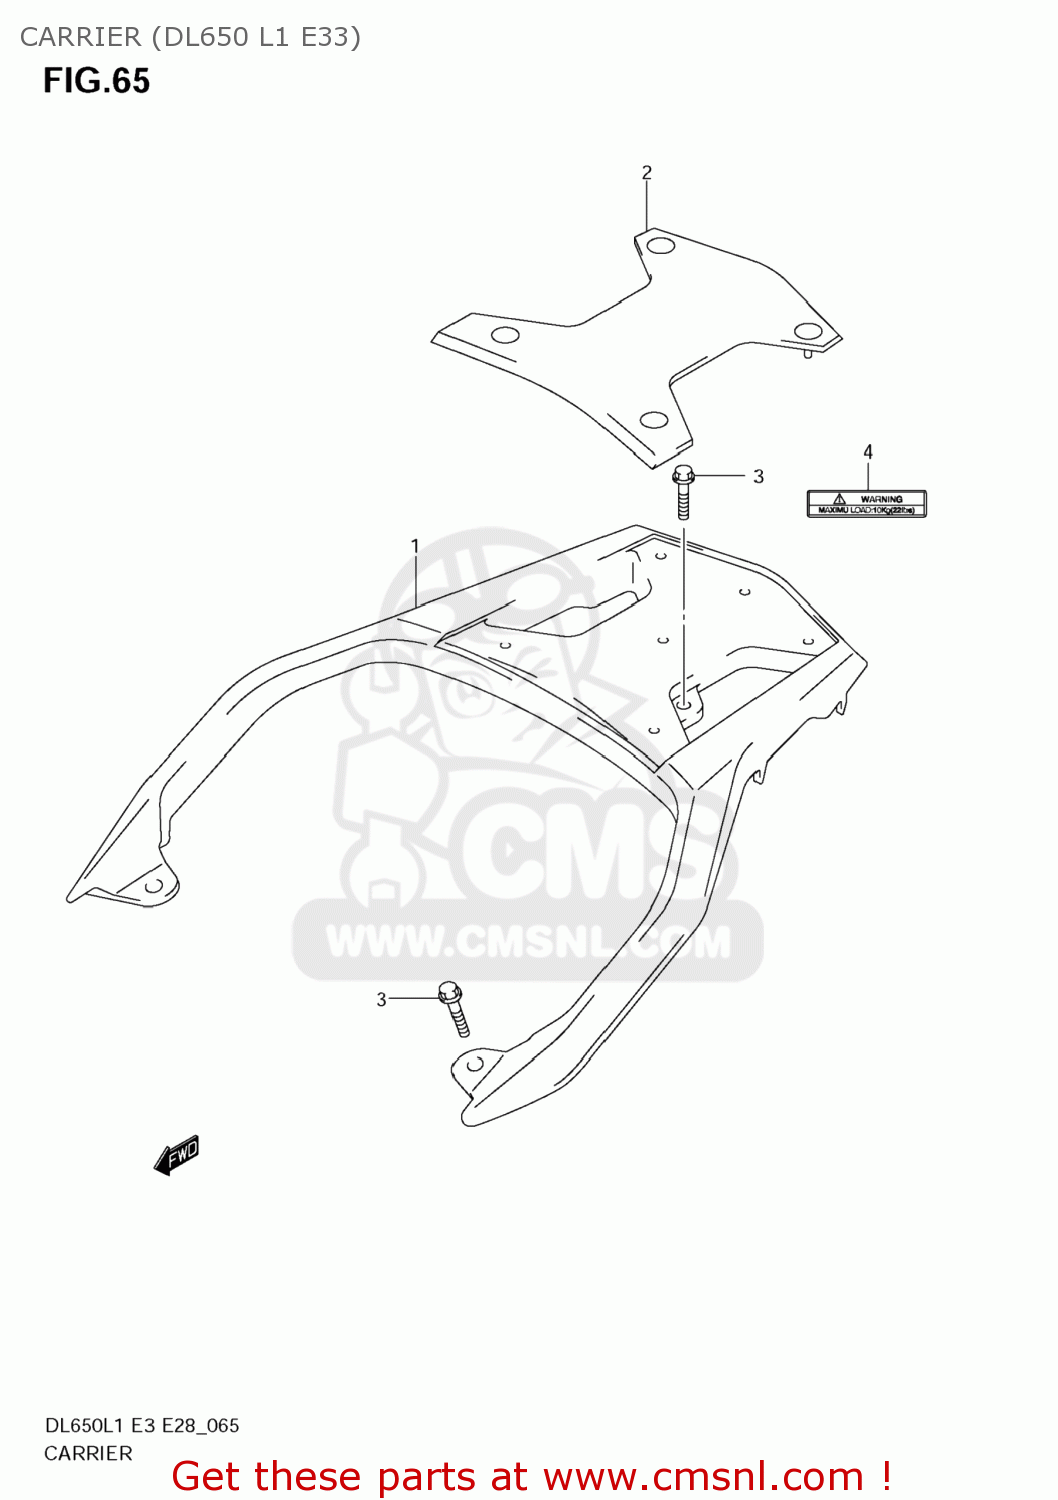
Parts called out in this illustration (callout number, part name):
1	CARRIER,SPORT
2	MAT,SPORT CARRIER
3	BOLT(8X35)
4	LABEL,WARNING LUGGAGE CARRIER
